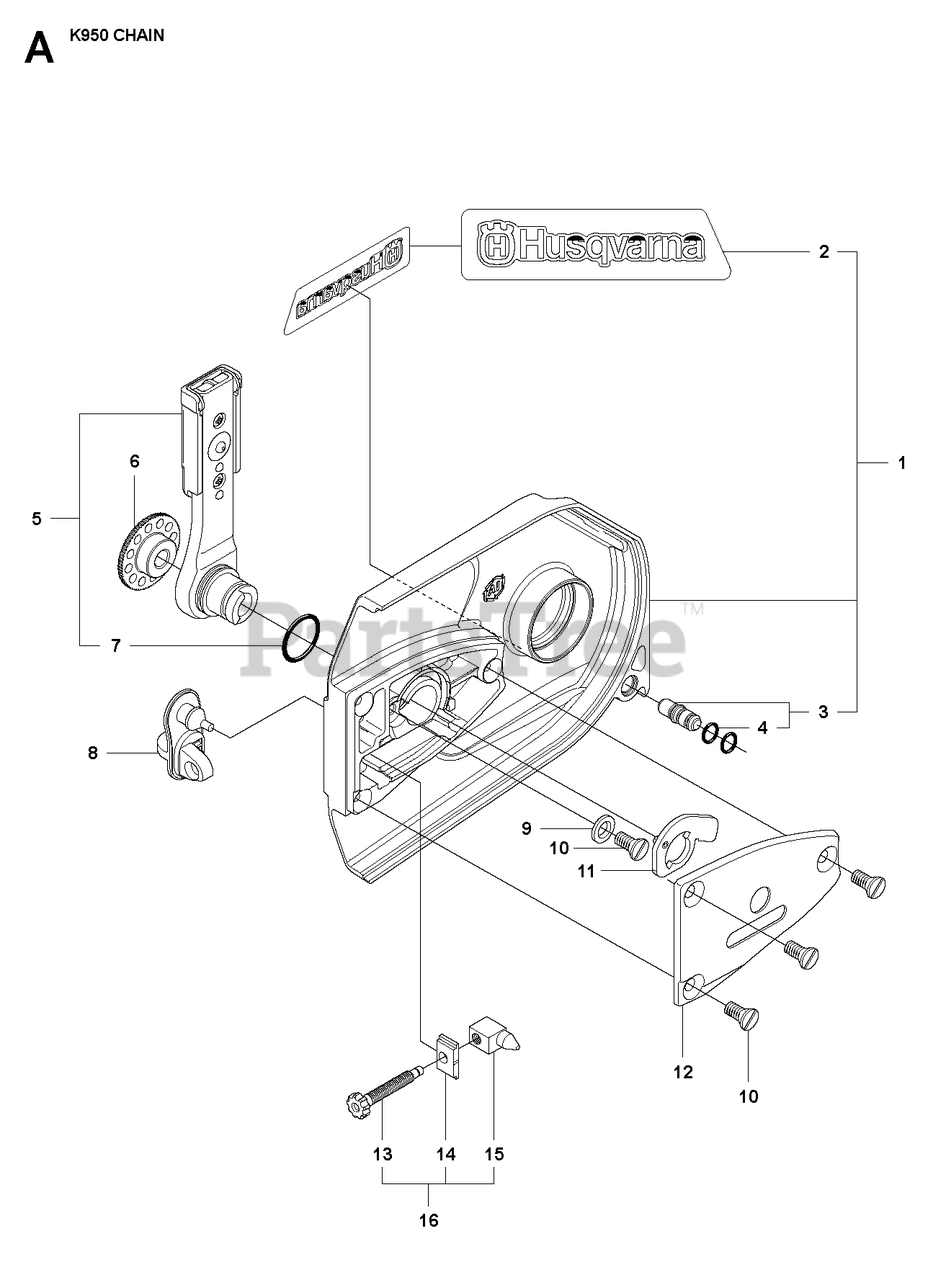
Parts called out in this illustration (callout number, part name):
1	CLUTCH COVERIncl. 2, 3
3	GUIDE PINIncl. 4
10	SCREW SLCSFM
16	SCREWIncl. 13, 14, 15
